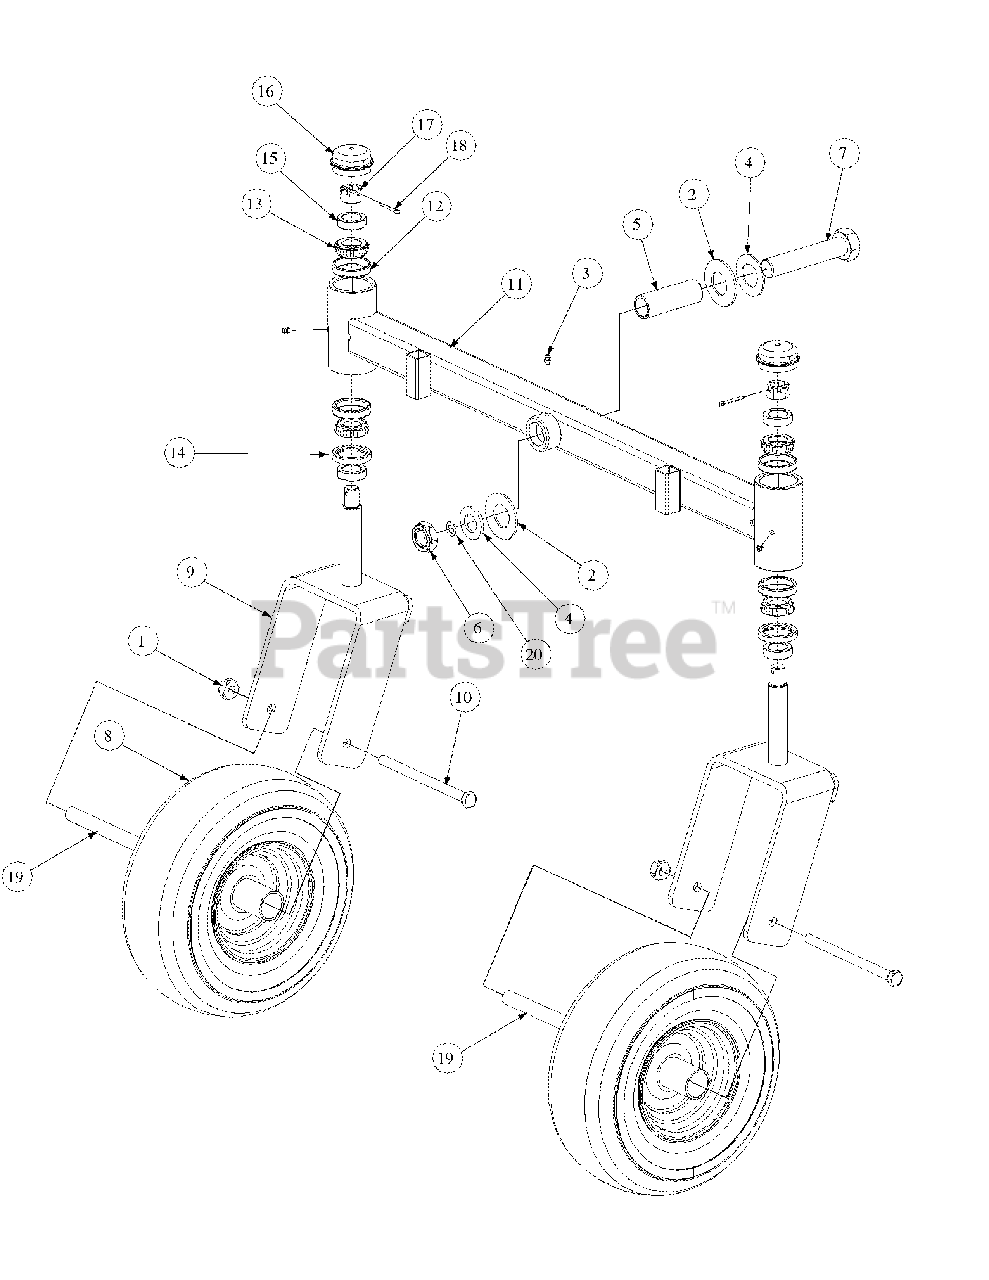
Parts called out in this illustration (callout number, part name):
1	Nut, 1/2-20, Center Lock
2	Bell Washer, 1.25 ID
3	Grease Fitting
4	Flat Washer, 1.00 ID
5	Spacer, 1.005 ID x 1.25 OD x 3.6
6	Nut, Jam, 1.0-14, Insert Lock
7	Hex Cap Screw, 1-14 x 5.0
8	Wheel, 13 x 5-6, White: Includes;
9	Yoke, Caster Wheel
10	HHCS, 1/2-20, 7.00
11	Straight Front Axle
12	Cup Bearing
13	Bearing Cone
14	Seal
15	Ring Seal
16	Grease Cap, 1.986 OD
17	Slotted Nut, 3/4-16
18	Cotter Pin, 5/32, 1.25
19	Wheel Spacer
20	Retainer Extension, Self Locking
